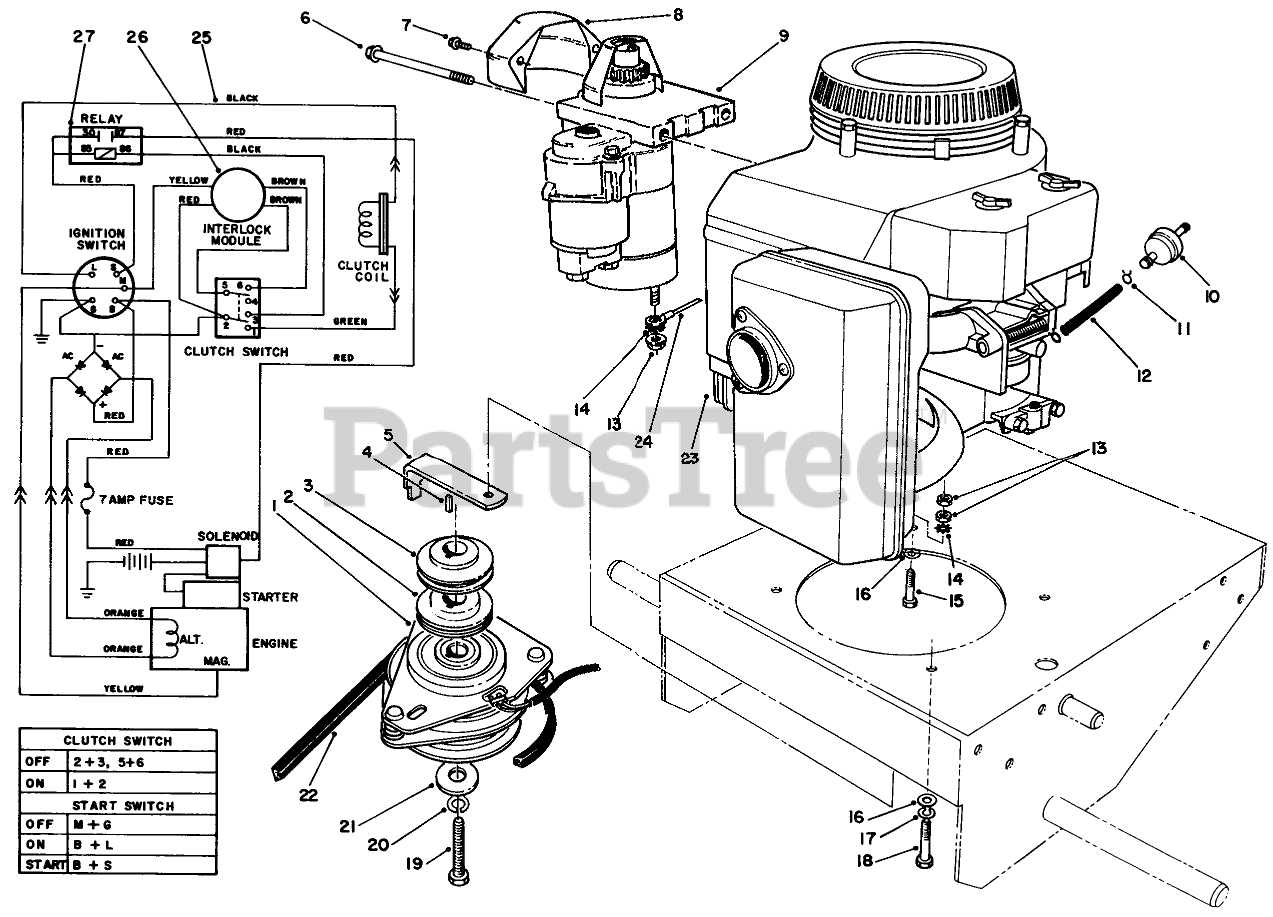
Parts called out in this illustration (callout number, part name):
1	CLUTCH/BRAKE
2	SHEAVE-LOWER HALF
3	SHEAVE-UPPER HALF
4	KEY-SQUARE
5	Retainer-Clutch
6	Screw-Hex. Hd. Cap
7	Screw-Hex. Hd. Cap
8	Cover
9	Motor-Starter/Alternator
10	FILTER-FUEL
11	CLAMP-HOSE
12	HOSE-FUEL
13	NUT-JAM
14	WASHER-LOCK
15	SCREW (ENGINE, GROUND)
16	WASHER-PLAIN
17	WASHER-LOCK
18	SCREW-HH
19	SCREW-CLUTCH
20	WASHER-LOCK
21	WASHER-CLUTCH
22	V-BELT, DRIVE
24	WIRE ASM
25	Wire Harness
26	Module
27	RELAY
